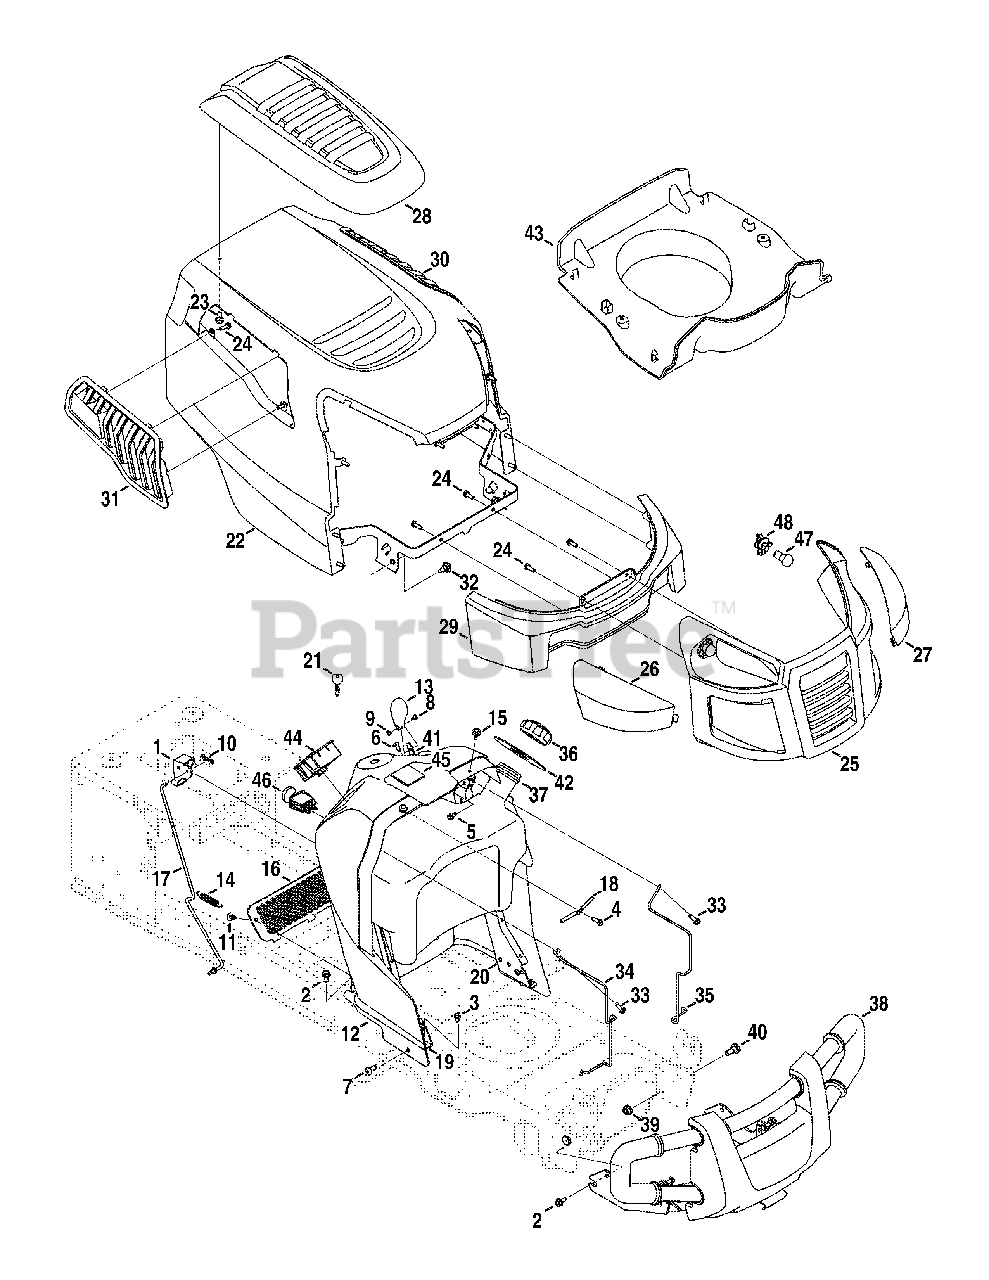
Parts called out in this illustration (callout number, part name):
1	Dash Lever
2	Taptite Screw, Lock Washer, 5/16-18:.750
3	Taptite Screw, Lock Washer, 1/4-20:0.500
4	Hi-Lo Screw, Lock Washer, 1/4-15:0.750
5	Screw, Lock Washer, 1/4-14:0.625
6	Screw, 1/4-14:0.625
7	Taptite Screw, 5/16-18:0.750
8	Machine Screw, #8-32:0.375
9	Hex Nut, #8-32 GR A
10	Bow-tie Cotter Pin
11	Ratchet Clip:.250 DIA
13	Control Knob
14	Extension Spring, .500 DIA X 2.733 LG
15	Bumper
16	Accessory Net
17	Control Rod Latch
18	Lever Rod
19	RH Dash Support Plate
20	LH Dash Support Plate
21	Key (Set of 2)
22	Hood Assembly
23	Hi-lo Screw, Lock Washer, 1/4-15:0.50
24	Screw, Lock Washer, 1/4 DIA:.750
26	RH Lens
27	LH Lens
28	Hood Scoop
29	Lower Grill
30	LH Hood Scoop
31	RH Hood Scoop
32	Shoulder Screw, .43X.29:TT:5/16-18
33	Taptite Screw, 1/4-20:0.750
34	RH Tank Support Rod
35	LH Tank Support Rod
36	Fuel Cap
37	Fuel Tank, 2.75 Gallons
38	Guard Assembly
39	Flangelock Nut, 3/8-16
40	Shoulder Bolt, .496 x .336:3/8-16
41	Throttle/Choke Control
42	Fuel Tank Gasket
43	P-Style Plen
44	Switch Key Module
45	Hour Meter
46	PTO Switch
47	Miniature Lamp, 12V
48	Lamp Socket
